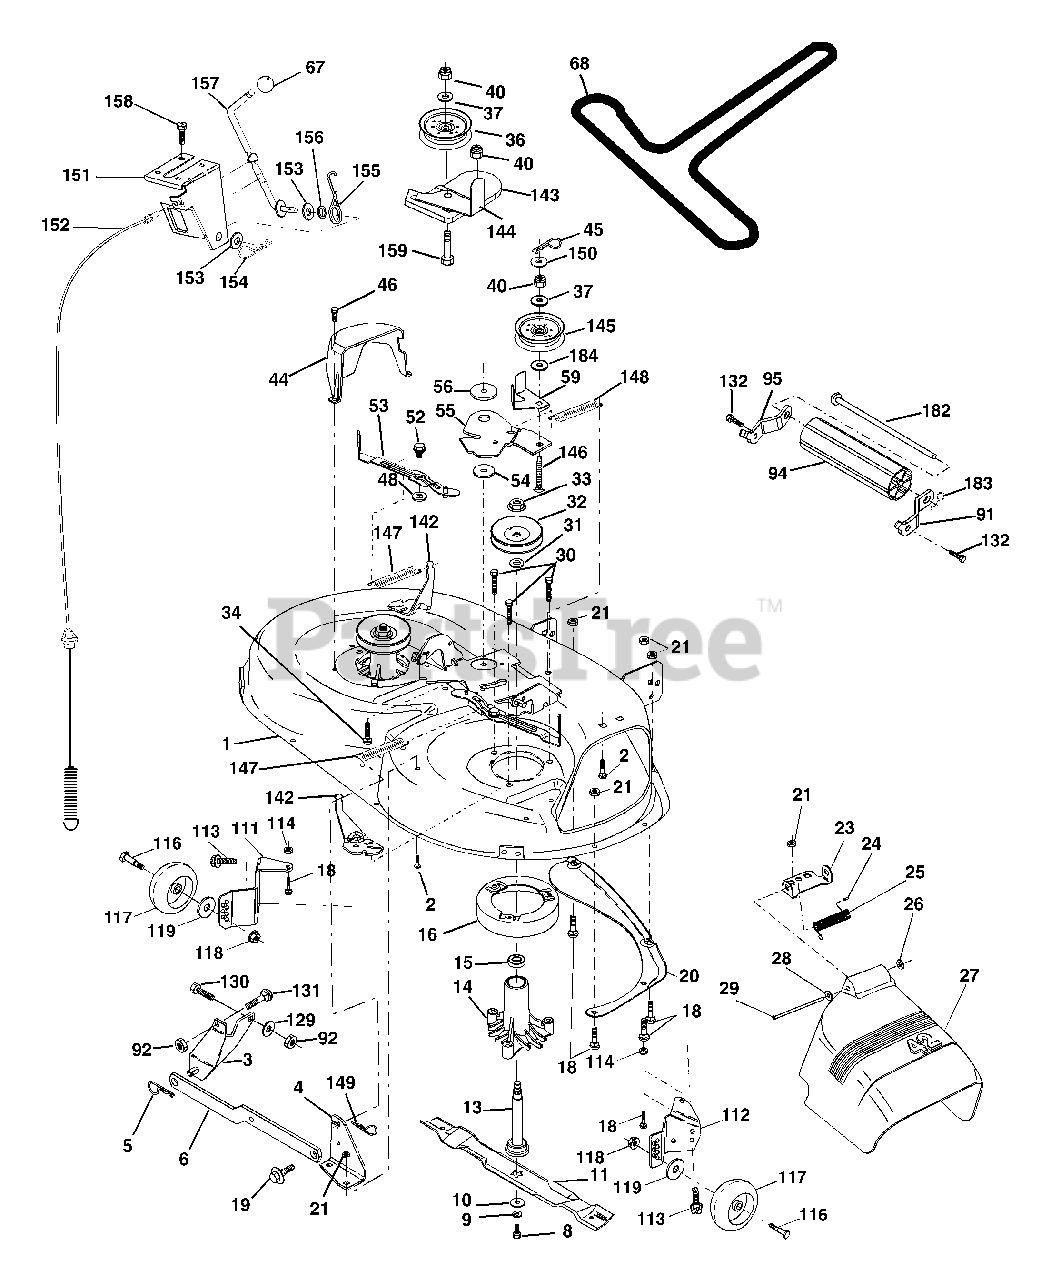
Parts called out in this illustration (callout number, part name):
1	Deck Asm MWR 42" weldment
2	Bolt Rdhd Sqnk 5/16-18unc X3/4
3	Bracket Asm Fr Sway Bar 38/42
4	Bracket Asm Deck 42" sway Bar
5	Retainer Spring
6	Deck Sway Bar
8	Bolt 3/8 - 24 X 1.25 Gr 8
9	Washer Lock Hvy 3/8
10	Washer Hard Blade Mower Vented
11	Blade, 42" Mulching Std
11	Blade, 42" Mulching Premium
11	Blade, 42" Hi-Lift
13	Shaft Asm W/lower Bearing
14	Housing Mandrel Vented
15	Bearing Ball Mandrel
16	Stripper Mower
18	Bolt Rdhd Sqnk 5/16-18 X 5/8
19	Bolt Shoulder
20	Baffle Vortex 42
21	Nut Crownlock 5/16-18 UNC
23	Bracket Deflector Mower 42"
24	Cap Sleeve 80x 112 Blk Mower
25	Spring Torsion Deflector 2 52
26	Nut Push Phos & Oil
27	Shield Deflector Mower 42" Blk
28	Washer 11/32 X 5/8 X 16 Ga
29	Rod Hinge 42" 6 75 Wlg
30	Screw Thd Rolling
31	Washer Spacer Mower Vented
32	Pulley Mandrel 42"
33	Nut Toplock Flng
34	Bolt Rdhd 3/8-16uncx1-3/4 Gr5
36	Pulley Idler Flat 3 060
37	Washer 13/32 X 13/16 X 16
40	Nut Crownlock 3/8-16 UNC
44	Guard Mandrel LH Black
45	Spring Retainer 1" Zinc/cad
46	Screw Hex Thd Cut 1/4-20 x 5/8 T
48	Washer Hardened Smaller
52	Bolt Shoulder 5/16-18 Unc Blkz
53	Arm Asm Pad Brake
54	Washer Hardened
55	Arm Idler 42" mower LT/YT
56	Spacer Retainer Mower
59	Guard TUV Idler
67	Knob Rd 3/8-16 Plstc Thds Blk
68	V-Belt Mower 42"
91	Bracket Roller Nose LH
92	Nut Lock Hex w/Ins. 3/8-16 Unc
94	Roller Nose
95	Bracket Roller Nose RH
111	Bracket Wheel Gauge LH 42" Deck
112	Bracket Gauge Wheel RH 42" Deck
113	Screw Tapping 3/8-16 x .625
114	Nut Keps 5/16-18 Unc
116	Bolt Shoulder
117	Wheel Gauge
118	Nut Centerlock 3/8-16 UNC
119	Washer 3/8 x 7/8 x 14 Ga.
129	Washer 13/32 x 13/16 x 12 Ga.
130	Bolt Rd Hd Sqnk 3/8-16 Unc x 1
131	Bolt Fin Hex 3/8-16 Unc x 1 Gr. 5
132	Screw Hex Wsh Thdr. 3/8-16 x 3/4
142	Arm Spring Brake Mower
143	Bracket Arm Idler 42"
144	Keeper Belt 42" Clutch
145	Pulley Idler Flat
146	Bolt Carriage Idler
147	Spring Extension
148	Spring Return Idler
149	Retainer Spring Yellow
150	Washer 9/32 x 3/4 x 16 Ga.
151	Bracket Clutch Cable
152	Clutch Cable 42"
153	Washer Flat 3/8" Type B
154	Spring Retainer
155	Spring Retention Lvr Cltch Cab
156	Spacer Clutch Cable
157	Rod Clutch Cable 3/8"
158	Screw Hex Thd Cut 1/4-20 x 1/2
159	Bolt Rdhd Sqn 3/8-16 Unc x 1-3/4
182	Rod Roller Nose
183	Retainer Spring
184	Washer 13/32 x 7/8 x 10 Ga.
